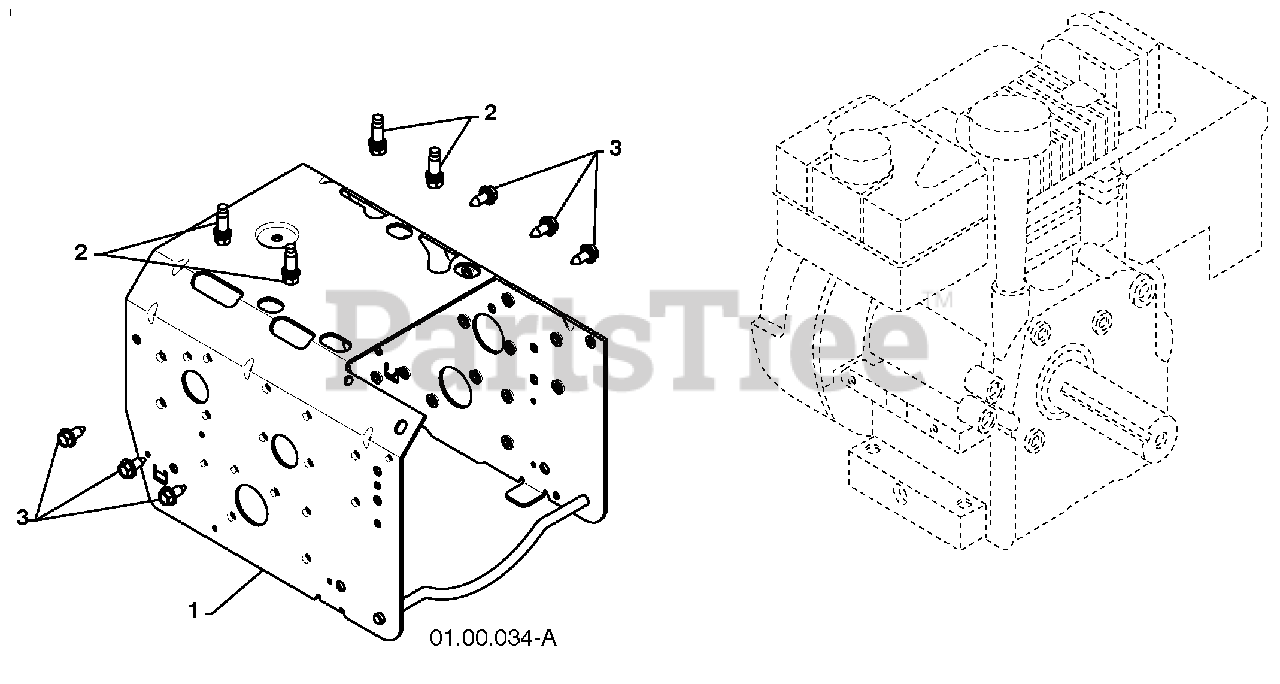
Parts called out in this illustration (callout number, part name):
1	FRAME
2	BOLT 3/8-16
3	SCREW 5/16-18 X .750
